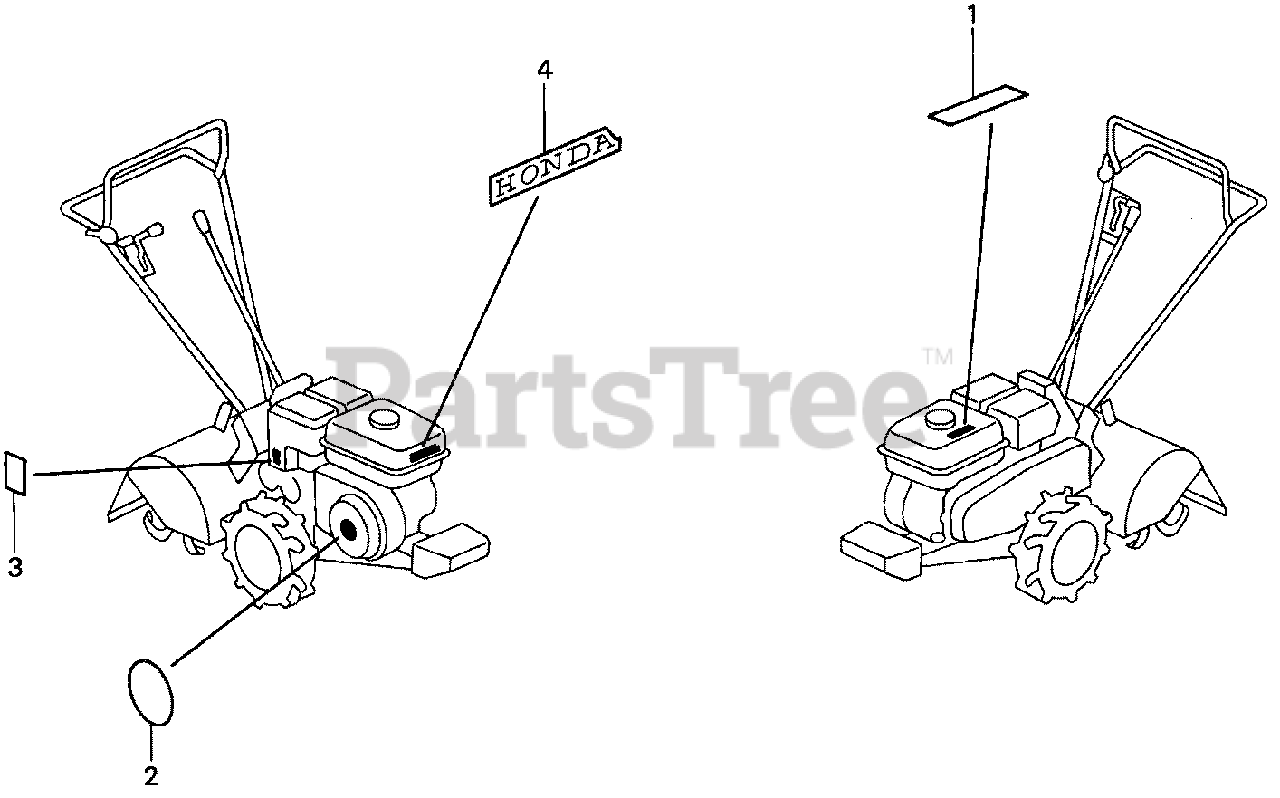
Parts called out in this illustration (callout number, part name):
1	LABEL, OPERATOR WARNING
2	PLATE, EMBLEM
3	MARK, CHOKE
4	MARK, HONDA (120)
